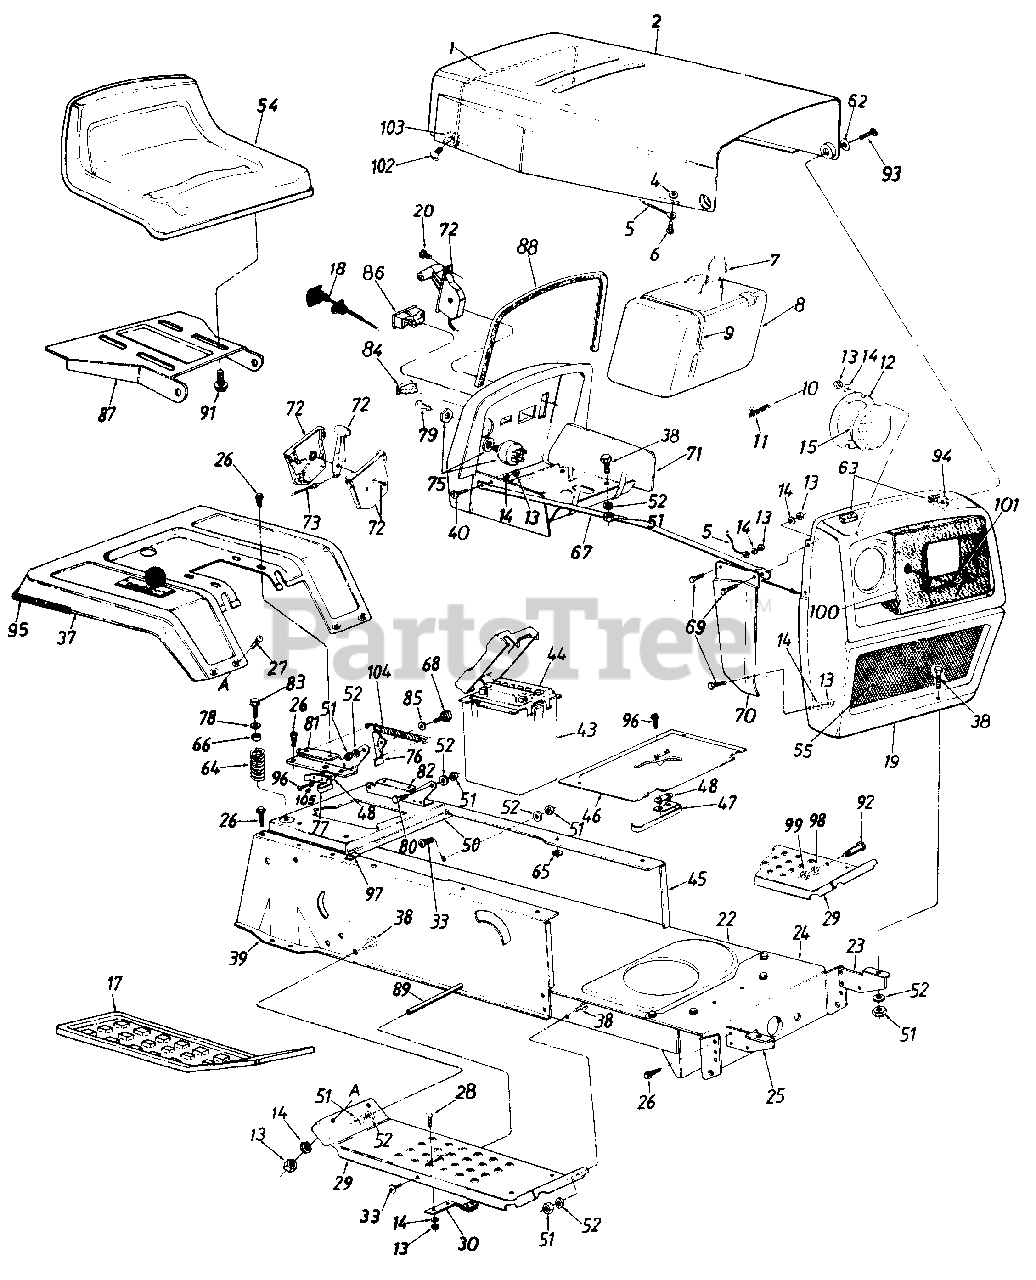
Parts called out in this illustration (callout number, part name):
5	Hood Stop 7n Lg.
6	POP Rivet
7	Fuel Cap Gauge
8	Fuel Tank
9	Tie Strap
10	Fuel Line
12	Headlight Retainer
13	Hex Nut 1/4-20 Thd.
14	L-Wash. 1/4" I.D.
15	Headlight
17	Foot Pad-L.H.
18	Choke Control 29" Lg.
19	Grille Ass'y.
20	Truss Mach. AB-Tap Scr. #10 x .50' Lg.
22	Lower Frame
23	Grille Mount Brkt.
24	Front Pivot Brkt.
25	Grille Mount Brkt.
26	Hex Wash. Hd. AB-Tap Scr. 5/16 x 75n Lg.
27	Carriage Bolt 1/4-20 x 2.0"
28	Carriage Bolt 1/4-20 x .62"
29	Running Board
30	Blade Brake Ass'y.
33	Truss Mach. Scr. 5/16-18 x .75 Lg.
39	R.H. Side Frame
40	Hex Bolt 1/4-20 x .62 Lg.
43	Battery Box w/Cover
44	12-V Battery
45	L.H. Side Frame
46	Shift Cover
47	Reverse Safety Switch
48	Insulator Nut Plate
50	Hitch Plate
51	Hex Nut 5/16-18 Thd.
52	L-Wash. 5/16" l.D.
54	Seat Ass'y.
55	Grille Insert
62	Washer .39" l.D. x .62" O.D.
63	Foam Strip 3/8 x 1-1/8 x 11/2
64	Compression Spring
65	Ext. L-Wash. 5/16" I.D.
67	Grille Support Rod-R.H.
69	Truss Hd. Scr. 1/4-20 x .75"
70	R.H.-Grille Side Panel
73	Throttle Control Wire
75	Ignition Switch
76	Seat Lift Bracket
77	Spring Switch
78	Fl-Wash. .344" l.D.
79	Ignition Key
80	Shld. Bolt .437" Dia. x .162"
81	Seat Pivot Brkt. Support-R.H.
82	Seat Pivot Brkt. Support-L.H.
83	Hex Hd. Tap Scr. 5/16-18 x 1" Lg.
84	Light Switch
85	Spr-Wash. .445n l.D. x .75" O.D.
86	Ammeter
87	Seat Pivot Bracket
88	Molding Strip 27" Lg.
89	Running Board Rod
91	Hex Wash. Hd. Tap Scr. 3/8-16 x .75" Lg.
92	Shld. Bolt .5n Dia. x 84n
93	Shld. Bolt .375 Dia. x .125
94	Hex L-Nut 1/4-28 Thd.
95	Trim Strip-81n
96	Hex Wash. Hd. AB-Tap Scr. #8 x .50n Lg.
97	Speed Nut #10Z
98	L-Wash. 3/8" I.D.
99	Hex Nut 3/8-16 Thd.
101	Oval C-Sunk Mach. Scr. 1/4-20 x 1.5" Lg.
102	Self-Tap Scr. .5n Lg.
103	Hood Spring Retainer
104	Extension Spring 5.31" Lg.
105	Fiber Washer
